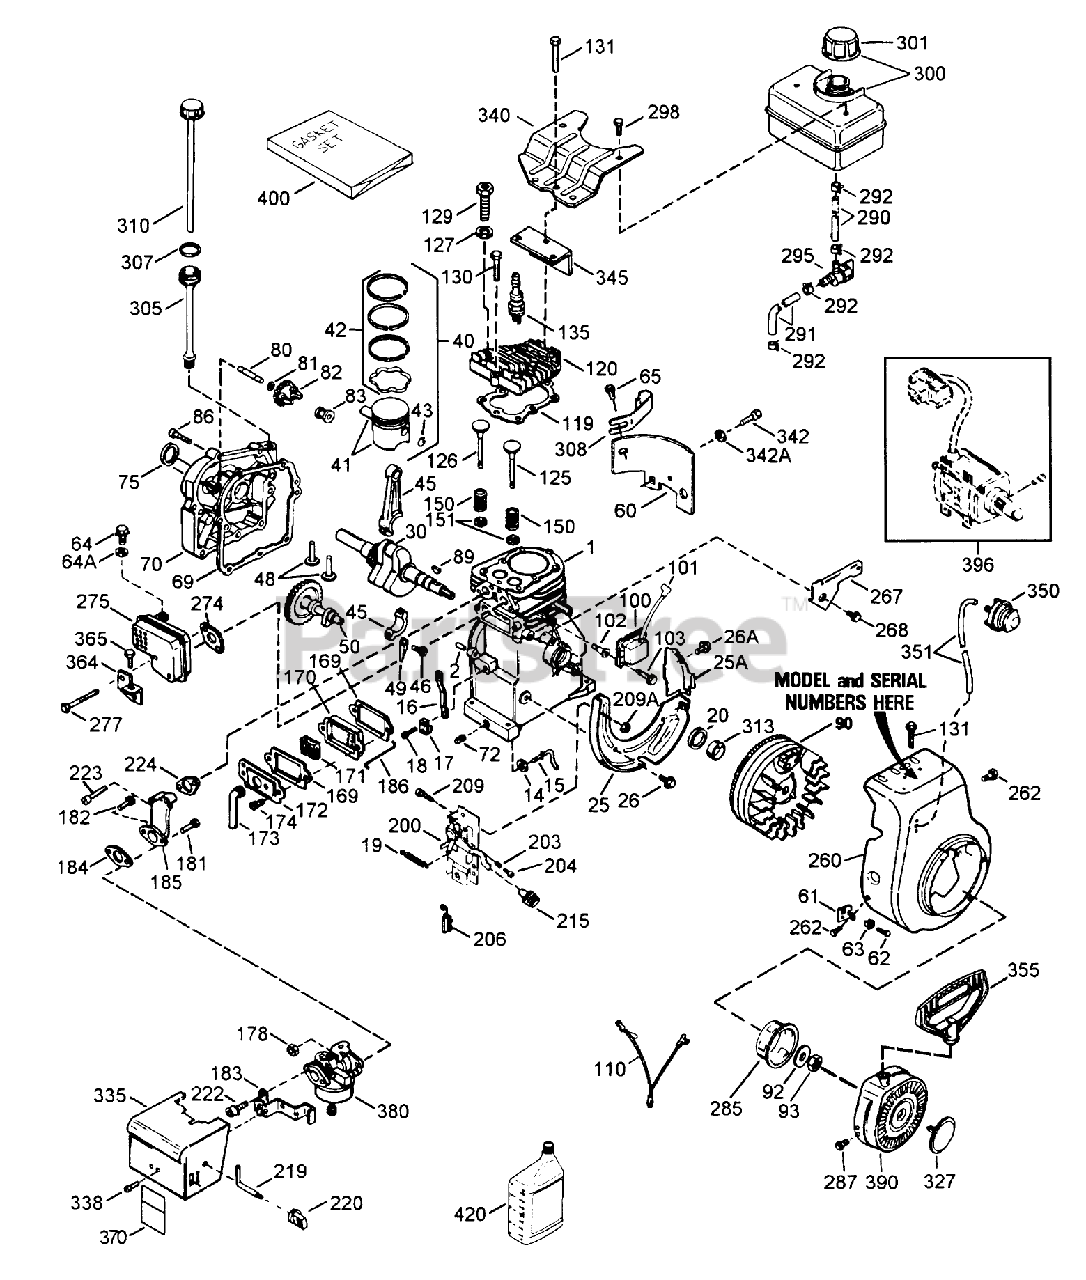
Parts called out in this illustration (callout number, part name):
1	Cylinder Assembly (Incl. Ref. #2, 20 72)
2	Pin-Dowel
14	Washer-Flat
15	Rod-Governor
16	Lever-Governor
17	Clamp-Lever, Governor
18	Screw
19	Spring-Extension
20	Seal-Oil
25	Baffle-Blower Housing
25A	Extension-Baffle
26	Screw (1/2-20x5/8)
26A	Screw (8-32 x 21/64)
30	Crankshaft ASM
40	Set-Piston, Pin Ring (Std)
41	Piston Pin Ass-y.(Std.)(Incl. 43)
42	Ring Set (STD)
43	Ring-Retaining, Piston Pin
45	Rod Assembly, Connecting (Incl. Nos. 17 18)
46	Bolt-Rod, Connecting
48	Lifter-Valve
49	Dipper-Oil
50	Camshaft
60	Extension-Blower
61	Bracket
62	Screw (8-32 x 3/8)
63	Grommet
64	Screw
64A	Washer
65	Screw
69	Gasket-Cover, Cylinder
70	Cover-Cylinder (Incl. Ref. #75 80)
72	Plug-Drain, Oil (SQH 1/4-18)
75	Seal-Oil
80	Shaft-Governor
81	Washer-Flat
82	Governor Gear ASM
83	Spool-Governor
86	Screw (1/4-20 x 1-1/4)
89	Key-Flywheel
90	Flywheel
92	Washer-Belleville
93	Nut-Flywheel
100	Solid State
101	Cover-Spark Plug
103	Screw
110	Wire-Ground
119	Gasket-Head, Cylinder
120	Head-Cylinder (Incl. Ref. #131)
125	Valve, Exhaust (Std.)(Incl. No. 40)
126	Valve-Intake Standard (Incl. Ref. #151)
127	Washer-Flat
129	Screw ( 5/16-18 x 1-1/2)
130	Screw (5/16-18x1-1/2)
131	Screw (5/16-18 X 2)
135	Spark Plug-Resistor (R J19 L M)
150	Spring-Valve
151	Cap-Valve, Spring
169	Gasket-Cover, Valve
170	Body-Breather
171	Element-Breather
172	Cover-Breather
173	Tube-Breather
174	Screw (10-24 x 9/16)
178	Nut and Lock Washer (1/4-28)
181	Screw (1/4-28 x 1-11/16)
183	Bracket-Choke
184	Gasket
185	Pipe-Intake
186	Link-Governor to Throttle
200	Control Assembly, Speed (Incl. Ref. #155 thru 158 160)
203	Spring-Compression
204	Screw
206	Terminal
209	Screw
209A	Nut-Lock
215	Knob-Control
219	Rod-Choke
220	Knob-Control
222	Screw (10-32 x 1/2)
223	Screw (1/4-20 x 1-19/32)
224	Gasket-Intake
260	Housing-Blower
262	Screw
267	Bracket-Hold Down
268	Screw (10-24 x 9/16)
272	Screw (10-24 x 3/8)
274	Gasket-Exhaust
275	MANUAL
277	Screw-Fil. Hd.
285	Cup-Starter
287	Screw (8-32 x 21/64)
290	Line-Fuel (8.62)
291	Line-Fuel
292	Clamp-Line, Fuel
295	Valve-Shut Off, Fuel
298	Screw (1/4-15x7/8)
300	Tank Assembly-Fuel (Incl. Ref. #250 253)
301	Cap-Fuel
305	Tube-Fill, Oil
307	O-Ring
308	Clip-Tube, Fill
310	Dipstick
313	Spacer
327	Plug Starter
335	Cover-Carburetor
338	Screw (8-32 X 5/16)
340	Plate-Fuel Tank
342	Screw
342A	Washer
345	Baffle-Heat
350	Primer-Asm
351	Line-Primer
355	Handle-Starter, Mitten Grip
364	Bracket-Cover, Carburetor
365	Screw (10-24 x 3/8)
370	Decal-Lubrication
380	Carburetor (Incl. Ref. #96)
390	Rewind Starter
396	Motor-Electric Starter
400	Gasket Set (Incl. Parts Marked *)(26756 (1), 27234A (2), 27272A (1), 27677A (1) 29673 (1), 36443 (1), 33670A (1), 33673A (1)
420	Oil-Engine (SAE 5W30)
